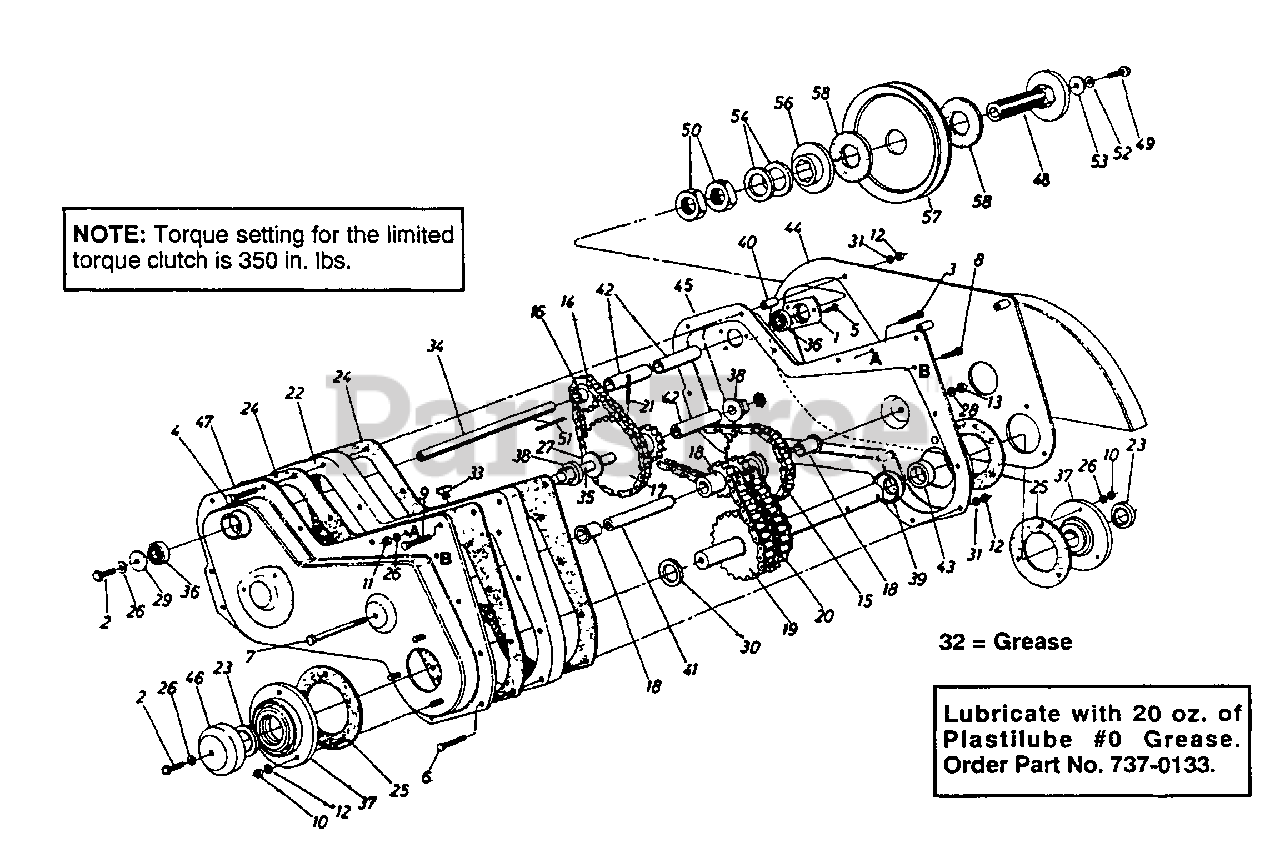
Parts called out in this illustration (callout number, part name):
1	Bearing Housing 1-3/8" Dia.
2	Hex Bolt 5/16-18 x .88" (Spec.)
3	Hex Bolt 5/16-18 x 1.5" Lg.
4	Hex Bolt 1/4-20 x 2.75" Lg.
5	Hex S-Tap Scr. 1/4-20 x .5" Lg.
6	Hex Bolt 1/4-20 x 1.5" Lg.
7	Hex Bolt 3/8-16 x 4.5" Lg.
8	Hex Scr. 1/4-20 x 1.5" Lg.
9	Hex TT-Tap Scr. 5/16-18 x 1.75"
10	Hex L-Nut 5/16-18 Thd.
11	Hex Nut 5/16-18 Thd.
12	Hex Nut 1/4-20 Thd.
13	Hex Nut 3/8-16 Thd.
14	#41 Chain 1/2" Pitch x 34 Links - Endless
15	#42 Chain 1/2" Pitch x 48 Links - Endless
16	Sprocket 10 Tooth .5" Pitch
17	10 & 28 Teeth Sprocket Ass'y.
18	8-2 & 28 Sprocket Sleeve Ass'y.
19	18-2 Sprocket Shaft Ass'y.
20	#50-2 Chain 5/8" Pitch x 28 Links - Endless
21	Spring Pin Spir. 1/4" Dia. x 1.5" Lg.
22	Spacer Block - Tiller Housing
23	Oil Seal 1-1/4" Dia.
24	Gasket for Tiller Housing
25	Gasket for Brg. Housing
26	L-Wash. 5/16" I.D.
27	Fl-Wash. .64" I.D. x 1.24" O.D.
28	L-Wash. 3/8" I.D. - H.D.
29	Fl-Wash. .344" I.D. x 1.125"
30	Special Washer
31	L-Wash. 1/4" I.D.
32	Grease - Plastilube #0 - 20 oz.
33	Vent Plug
34	Jack Shaft .525" I.D. x 7.78"
35	Sprocket Shaft .63" Dia. x 5"
36	Ball Brg. .62" I.D. x 1.38" O.D.
37	Bearing Housing - 1-1/4"
38	Hex Flange Brg.
39	Spacer 1.25" I.D. x 2.0" O.D.
40	Spacer .9" Lg.
41	Spacer 3.44" Lg.
42	Spacer .62" x
43	Spacer .5" Lg.
46	Dust Cap
49	Hex Bolt 5/16-18 x 1.25" Lg. Grade 5
50	Hex Jam Nut 1.0-14 x 28 Thd.
51	Sq. Key 3/16 x 1.5" Lg.
52	L-Wash. 5/16" I.D.
53	Fl-Wash. .344" I.D. x 1.125"
54	Bell-Wash. 1.0" I.D. x 2.0"
56	Floating Disc 3-1/4" O.D.
57	5/8 V-Pulley 1.5" I.D. x 6.5"
58	Friction Pad 3-1/4" O.D. x 1-3/8" I.D.
